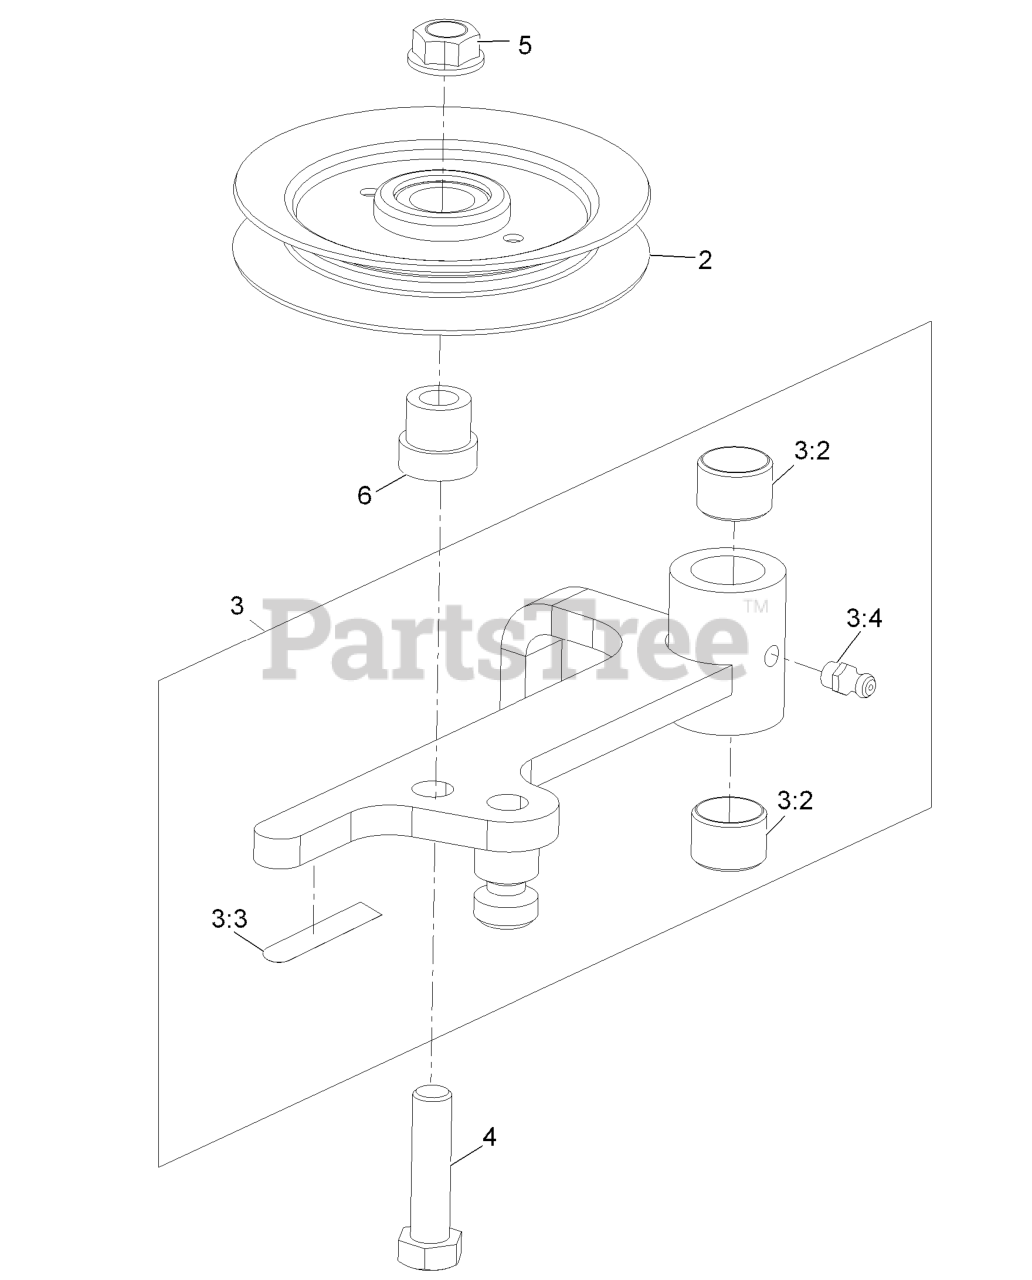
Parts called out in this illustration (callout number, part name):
3	ASM, IDLER ARM - SERVICE
3:2	BUSHING
3:3	DECAL-WARNING
3:4	FITTING-GREASE
4	SCREW-HH
5	NUT-HHF, WHIZ
6	HUB,SPACER
